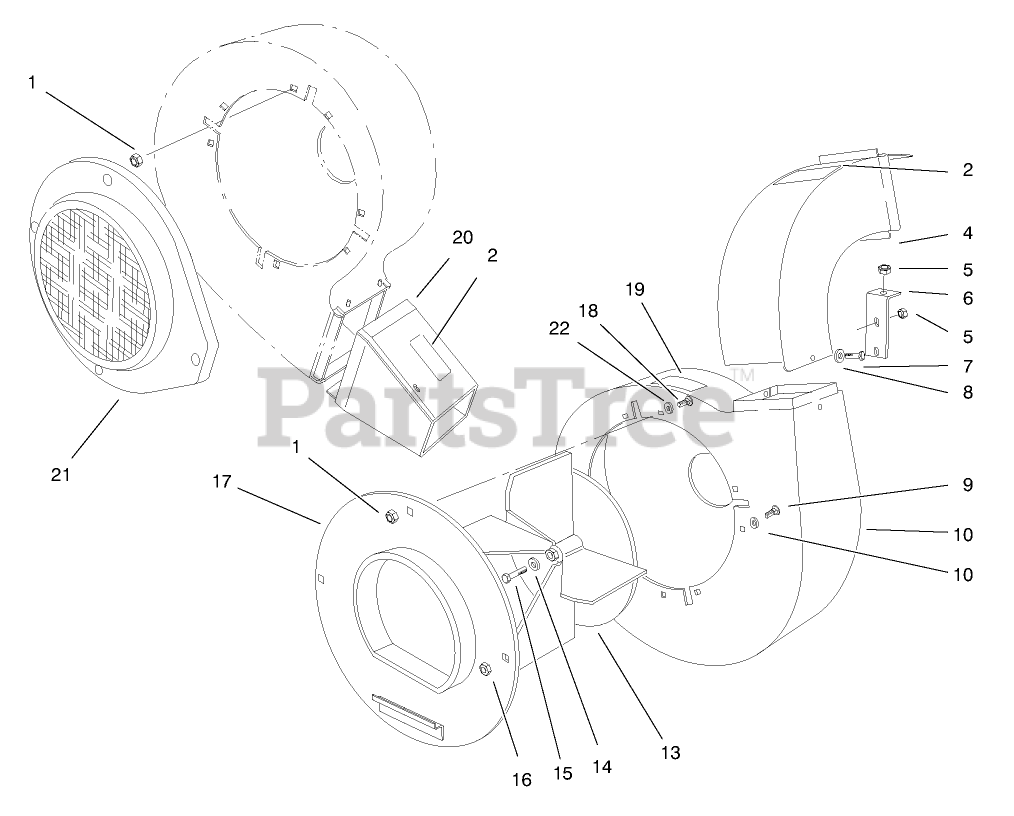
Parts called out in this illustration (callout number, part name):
1	NUT-FLANGE
2	DECAL-CAUTION, BAG
5	NUT-LOCK, NI
7	SCREW-HH
8	WASHER-BELLEVILLE
9	BOLT-CARR
14	WASHER-BELLEVILLE
15	SCREW-HH
16	NUT-LOCK, NI
18	BOLT-CARRAIGE
21	INTAKE-BLOWER
22	WASHER-FLAT
